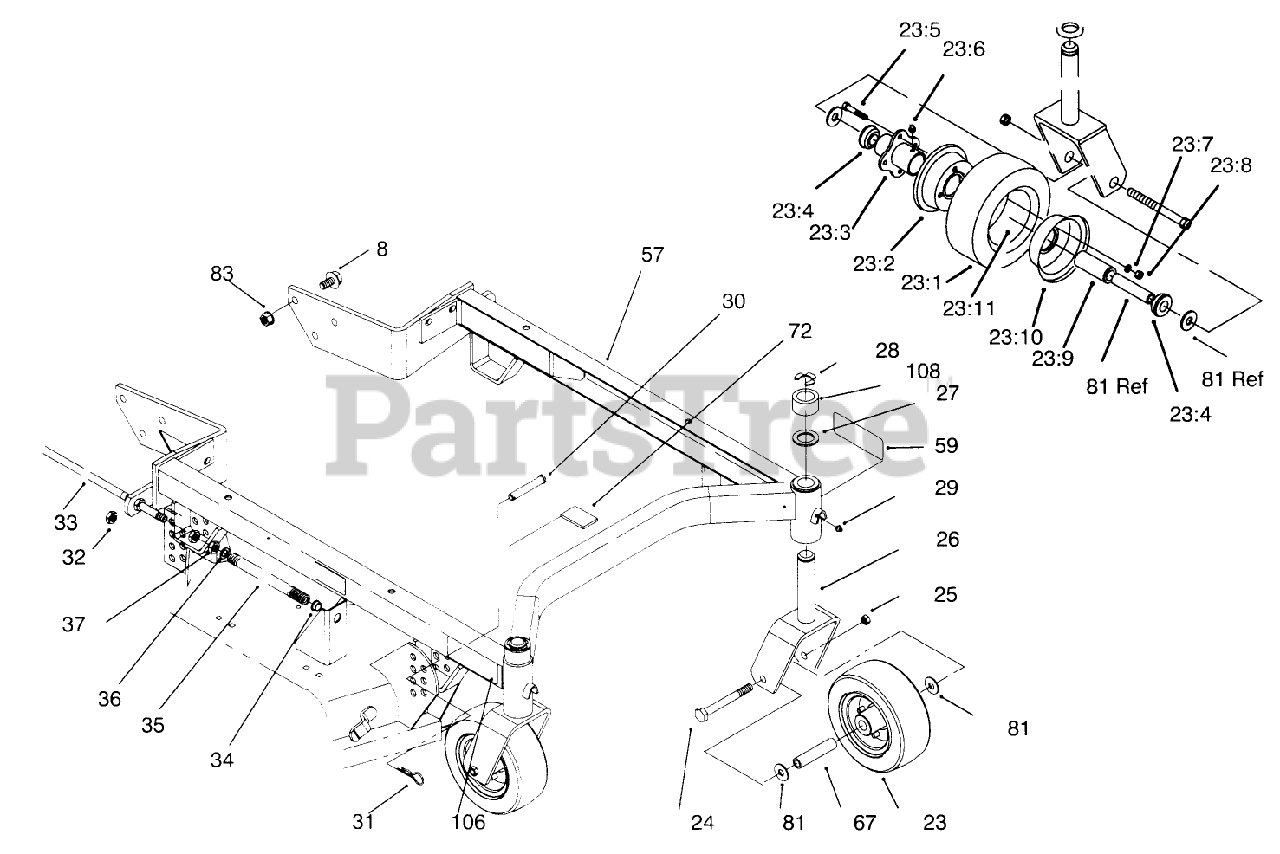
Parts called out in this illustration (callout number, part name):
23:2	FEMALE WHEEL HALF
23:3	HUB-CENTER
23:4	BEARING-OUTSIDE
23:5	WHEEL BOLT
23:6	FITTING-GREASE
23:7	WASHER-LOCK
23:8	NUT-HEX
23:9	BEARING-ROLLER
23:10	MALE WHEEL HALF
23:11	TUBE-INNER (W/VALVE)
24	SCREW-HH
25	NUT-HEX
27	WASHER-THRUST
28	RING-RETAINING
29	FITTING-GREASE
30	PIN-CLEVIS
31	PIN-HAIR
32	NUT-HEX
33	SHAFT-ADJUSTING
34	BUSHING-FLANGE
35	SPRING
36	WASHER
37	NUT-JAM
57	44IN FRAME ASM
59	DECAL-HOC, LH
67	SPANNER-TIRE
68	Plate-Serial
69	RIVET-POP
72	CUSHION-RUBBER
81	WASHER-FLAT
82	SCREW-HHF
83	NUT-HF
106	DECAL-HOC, RH
108	SPACER-CASTOR
